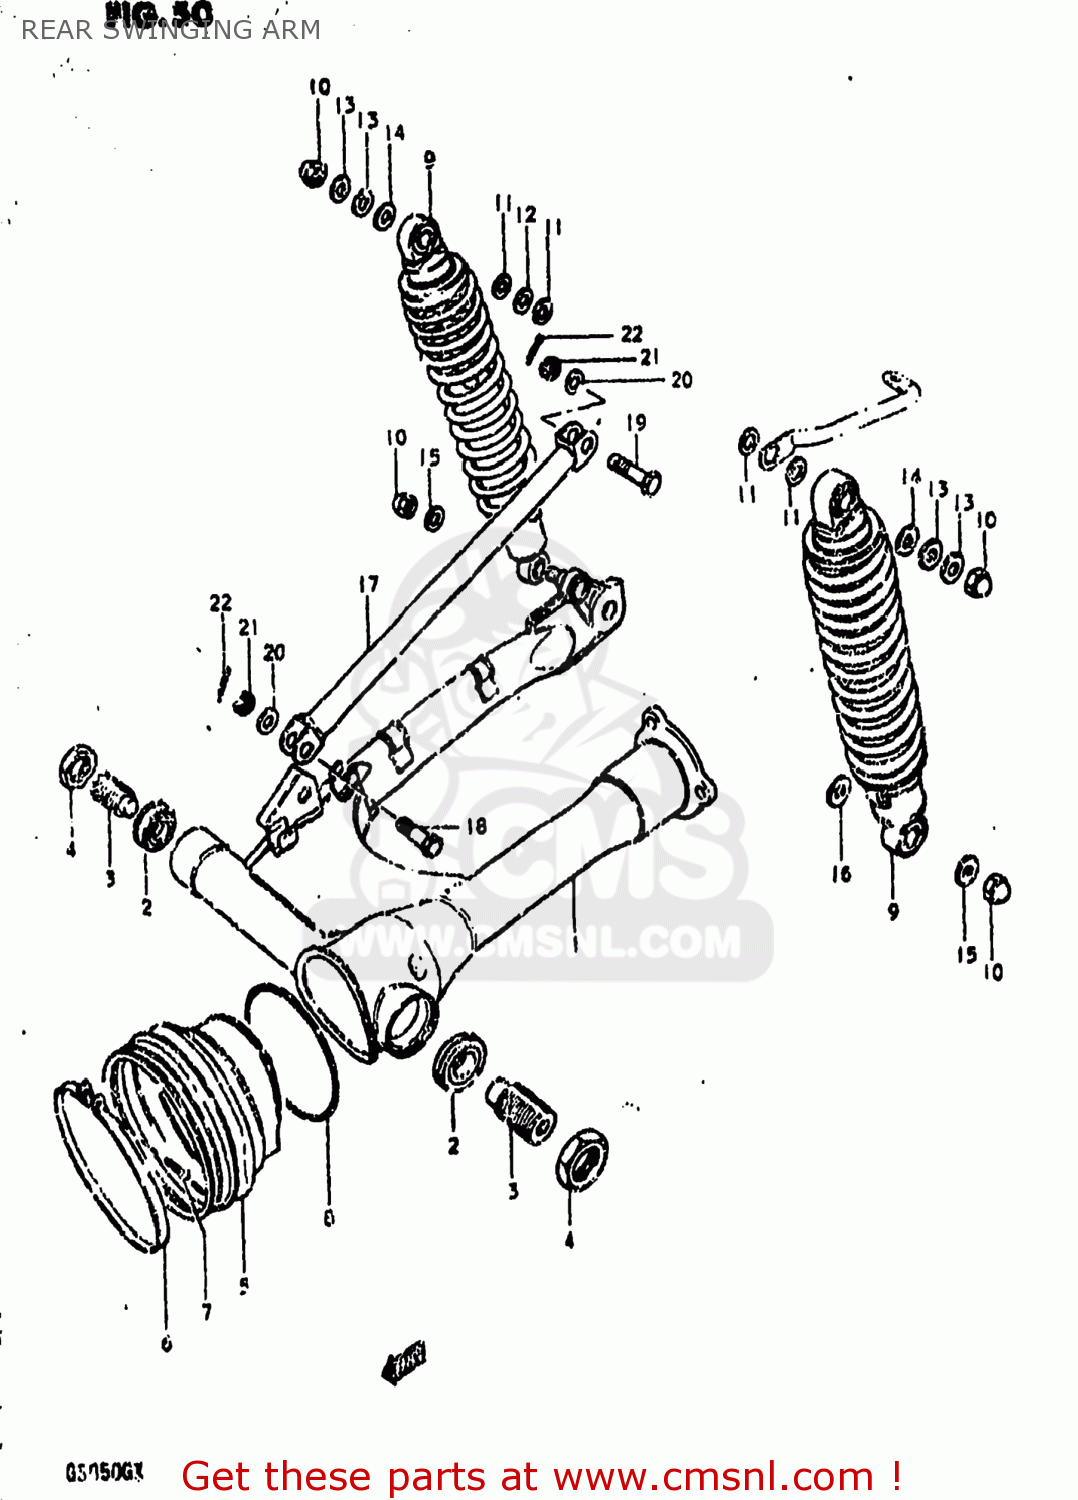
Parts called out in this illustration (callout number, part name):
1	SWING ARM ASSEMBLY,REAR
2	BEARING(17X40X13.25)
3	BOLT,REAR SWING ARM PIVOT
4	NUT
5	BOOT,PROPELLER SHAFT
6	CLAMP
7	SCREW 4X25
8	SPRING,PROPELLER SHAFT
9	ABSORBER ASSEMBLY,REAR SHOCK
10	NUT, LOWER LH
11	WASHER
12	WASHER (12.5X24X3.2)
13	WASHER
14	WASHER(10.5X24X3.2)
15	SPACER(10.5X16X30)
16	WASHER
17	LINK,REAR TORQUE
18	BOLT
19	BOLT(10X39)
20	WASHER
21	NUT
22	PIN 20X20
